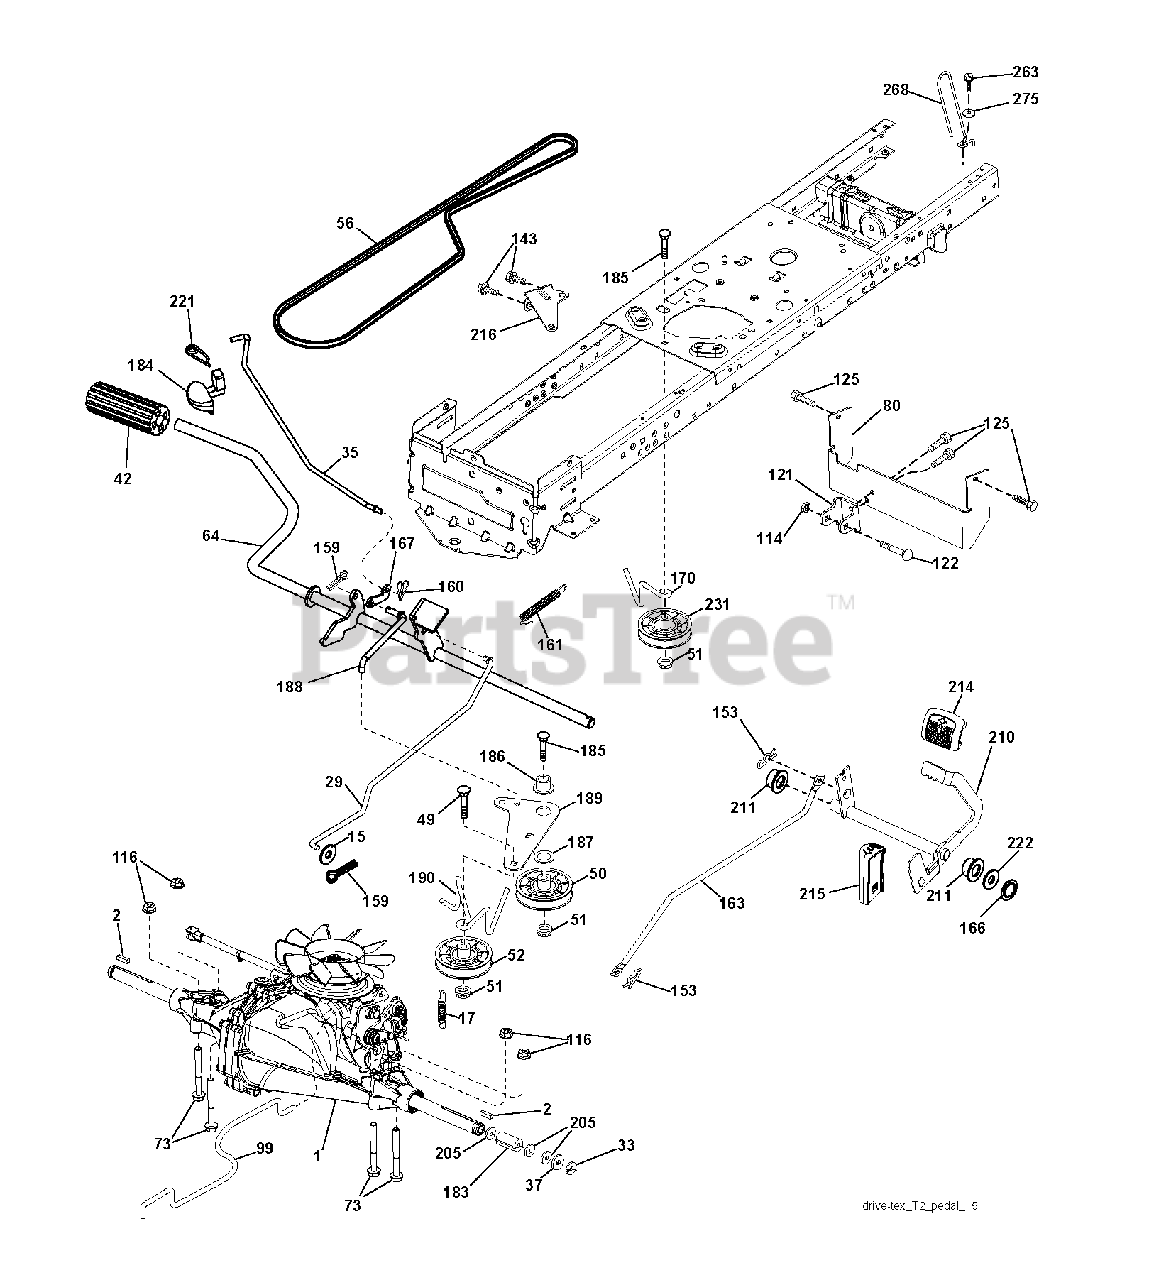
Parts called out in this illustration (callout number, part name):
2	SQUARE KEY
17	SPRING.BRAKE.HG3000/3500
29	ROD.BRAKE.T2.TEX
33	E-RING LT
35	ROD, BRAKE, PARK
42	PEDAL COVER T
49	BOLT
50	IDLER.FLAT.910.OFFSET
51	NUT LOCK FLG 3/8-16 UNC
52	IDLER.V-GROOVE.910.OFFSET
64	SHAFT.ASM.PEDAL.BRK.CNTR
73	BOLT HEX 5/16-18 GR 5
80	STRAP.TORQUE.FS.T2
99	ROD.ASM.BYPASS.SPRING.T2.FS
114	NUT.71038.31-18.HEX.NYLOCK
116	NUT LOCK HEX FLANGE 5/16-18
121	BRACKET STRAP TORQUE
122	BOLT.5/16-18X2.5
125	SCREW
153	RETAINER M
159	COTTER PIN
160	RETAINER CLIP
161	SPRING, RETURN LT
163	ROD.CONTROL.PCH.T2.TEX
166	NUT.PUSH.625.2006
167	LATCH.BRAKE.SPRING
170	KEEPER.CENTER SPAN.1.688
183	SPACER, AXLE PVST
184	HANDLE PARKING BRAKE
186	SPACER.RETAINER
187	WASHER 12/32X2X10GA
188	LINK.CLUTCH.GROUND.DRIVE
189	BELLCRANK.GROUND.DRIVE.TEX.
190	KEEPER.BELLCRANK.DRIVE
210	ROCKER.ASM.PEDAL.CONTR
211	BEARING.NYLON
214	PAD PEDAL FORWARD
215	PEDAL.REVERSE.TEX.GT.4
216	BRACKET.PULLEY.IDLER.W/TEX
221	RETAINER.SPRING.CLIP.H
222	WASHER 21/32 X 1-1/4 X 10 GA.
231	IDLER.V-GROOVE.1.688.OFFSET
263	SCREW, 3/8-16X3/4
275	WASHER
